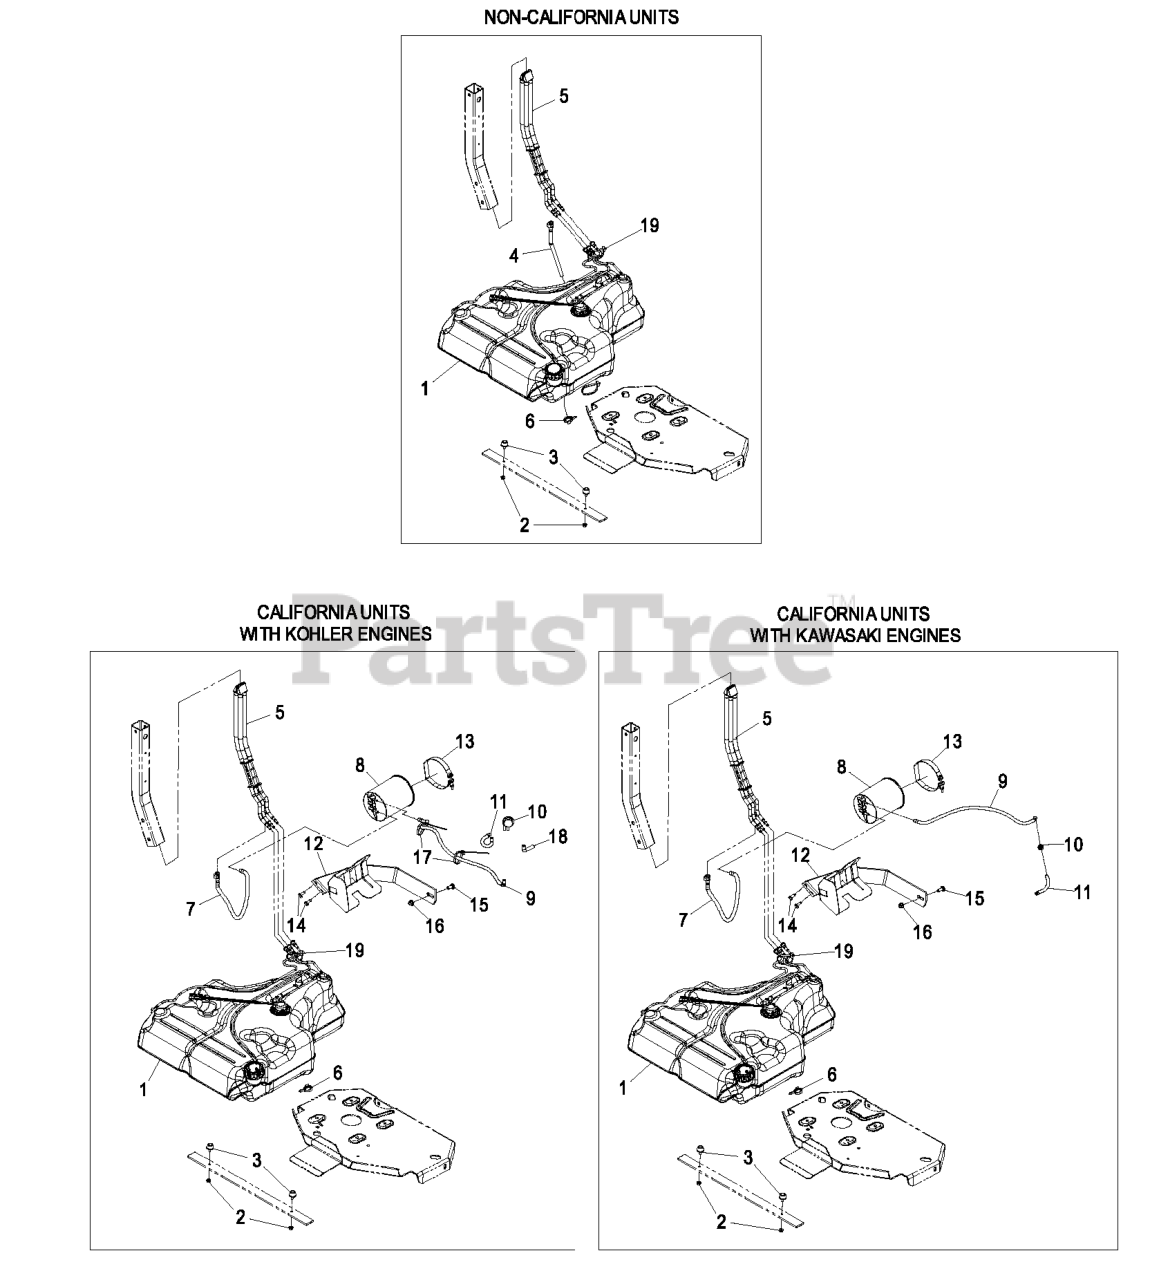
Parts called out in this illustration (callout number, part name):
3	BUMPER-RUBBER
4	TUBE-VENT, FUEL DRAIN
5	FUEL MANIFOLD VENT ASM
6	CLAMP-HOSE
7	VENT HOSE ASM
8	CANISTER-CARBON, 1200CC
9	HOSE-LP
11	HOSE-VENT, FORMED
12	MOUNT-CANISTER
13	CLAMP, T-BOLT
14	Screw-HWH 5/16-18 X 3/4 Tf
15	SCREW-CARR
16	NUT-HF, NI
17	TIE-PLASTIC
18	HOSE-VENT, FORMED
19	TIE-PLASTIC
